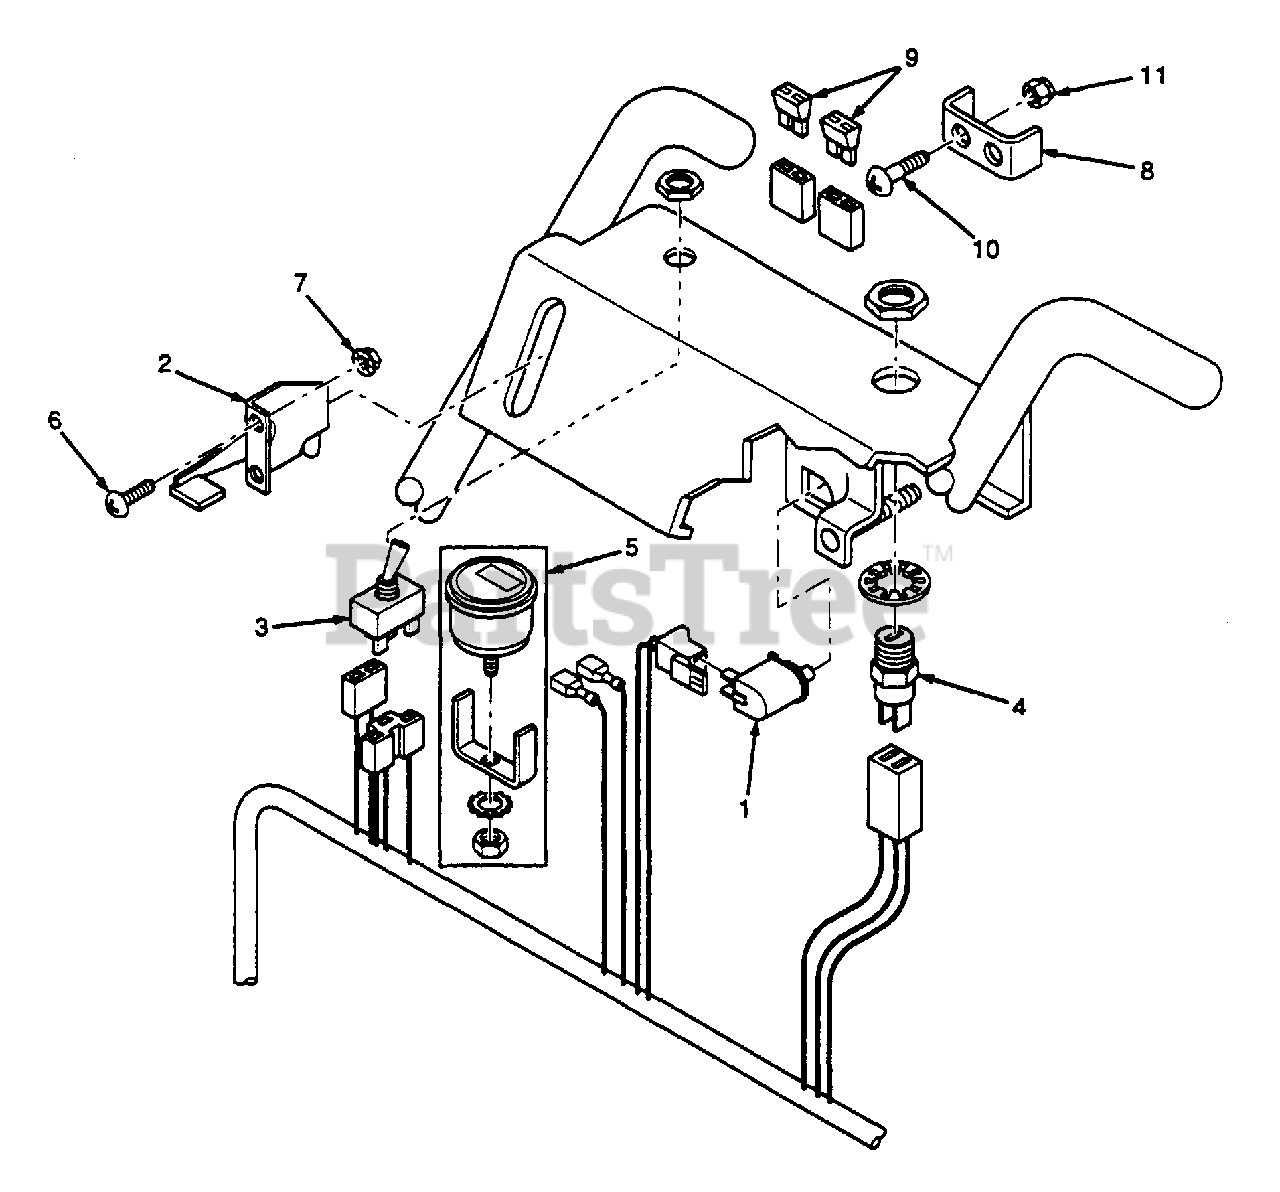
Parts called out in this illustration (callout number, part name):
1	Switch, Neutral Interlock
2	Throttle Control
3	Engagement Switch, Electric Clutch
4	Key Switch
5	Hour Meter
6	Screw, #10-32 x .50 Phillips Washer Head
7	Nut, 5/16-18 Serrated Flange Hex Head
8	Bracket, Fuse Holder
11	Nut, #10-32 Elastic Stop
12	Spring, Operator Presence
